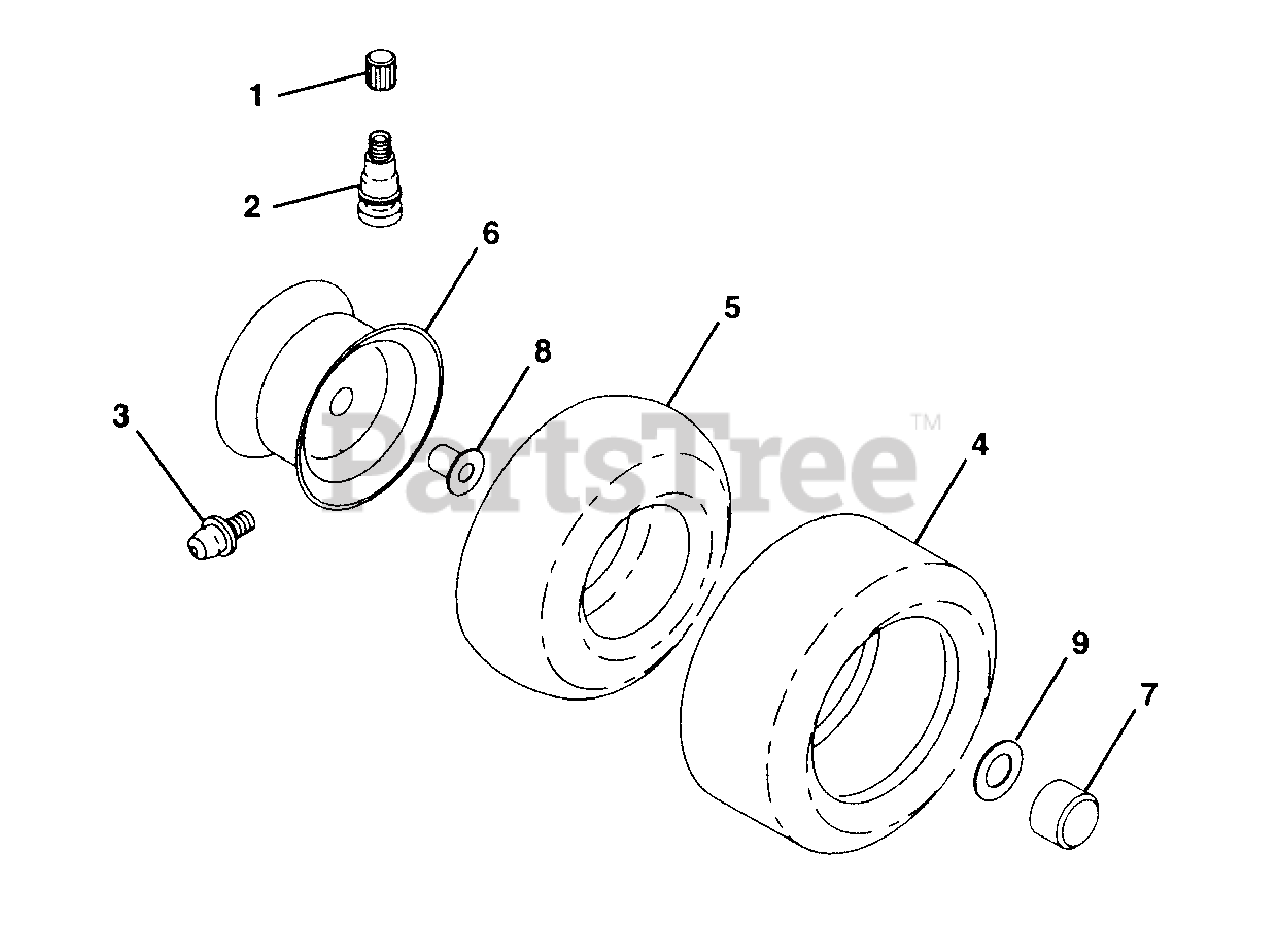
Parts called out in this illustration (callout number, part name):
1	Cap, Valve
2	Stem, Valve
3	Fitting, Grease
4	Tire, Front
4	Tire, Rear
5	Tube, Front
5	Tube, Rear
6	Rim, Front
8	Bearing Flange
9	Washer 25/32 x 1-5/8 x 16 Ga.
